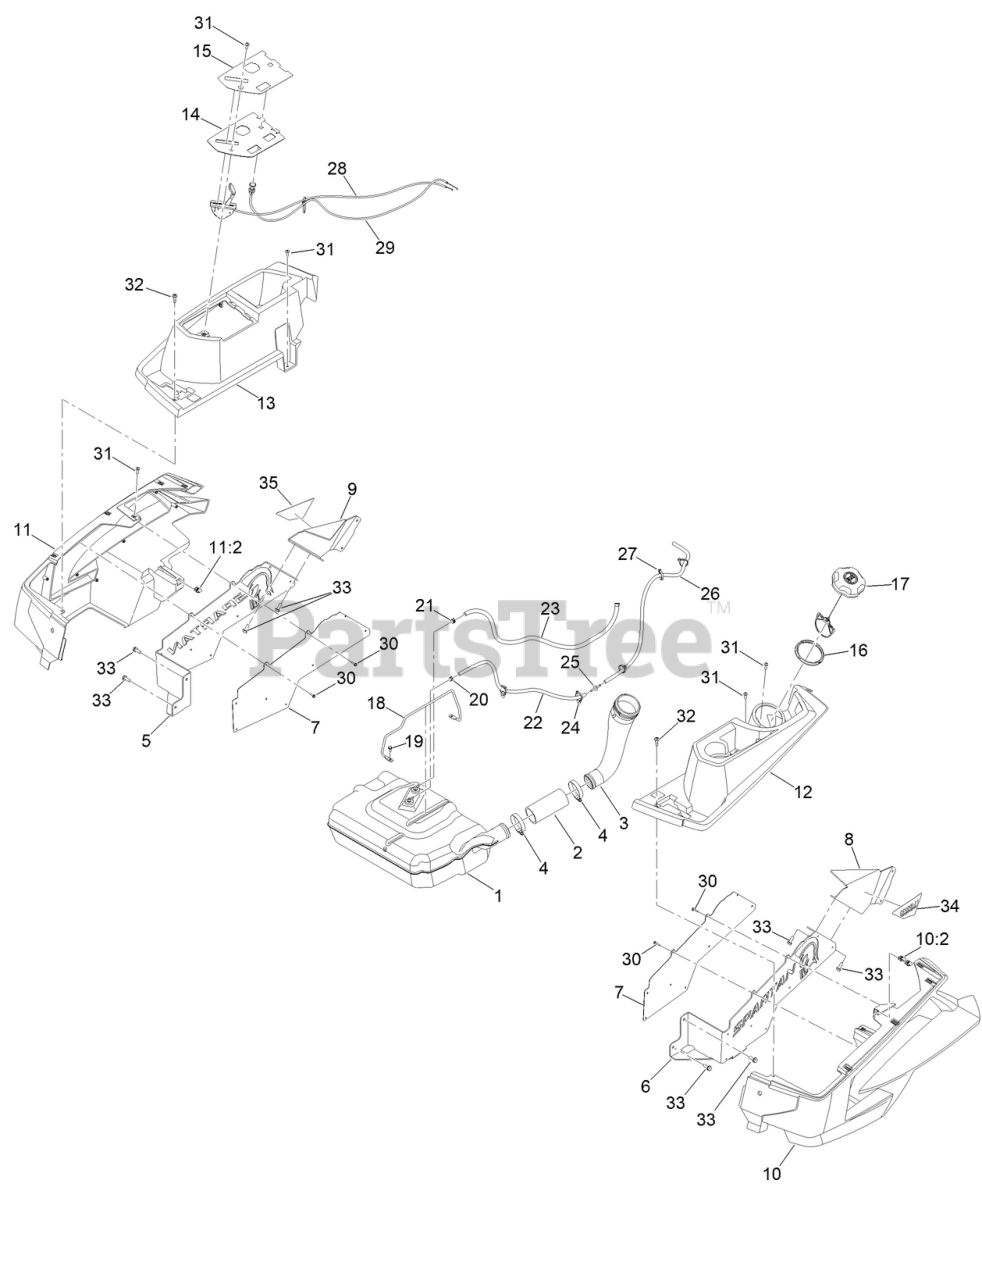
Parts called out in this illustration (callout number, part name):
1	FUEL TANK ASM
2	HOSE-FILLER, FUEL
3	NECK-FILLER, FUEL
4	CLAMP-HOSE
5	BRACKET-MOUNT, RH POD
6	BRACKET-MOUNT, LH POD
7	PLATE-BACK
8	BRACKET-MOUNT, LH POD
9	BRACKET-MOUNT, RH POD
10	LH POD ASM
11	RH LOWER POD W/DECAL ASM
12	LH UPPER POD W/DECAL ASM
13	RH UPPER POD W/DECAL ASM
14	PLATE-CONTROL
15	DECAL-CONTROL PANEL
16	RING-RETAINING
17	CAP-FUEL, RATCHETING
18	ROD-HOLD DOWN
19	SCREW-HWH
20	CLAMP-HOSE
21	CLAMP-HOSE
22	HOSE-FUEL
23	HOSE-FUEL
24	CLIP-TIE
25	ADAPTER ORIFICE
26	HOSE-LP
27	TIE-CABLE
28	CABLE-THROTTLE
29	CABLE-CHOKE
30	SCREW-PLASTITE, HWH
31	SCREW-PH
32	SCREW-TORX
33	SCREW-TAPTITE
34	DECAL-SHIELD, LH
35	DECAL-SHIELD, RH
